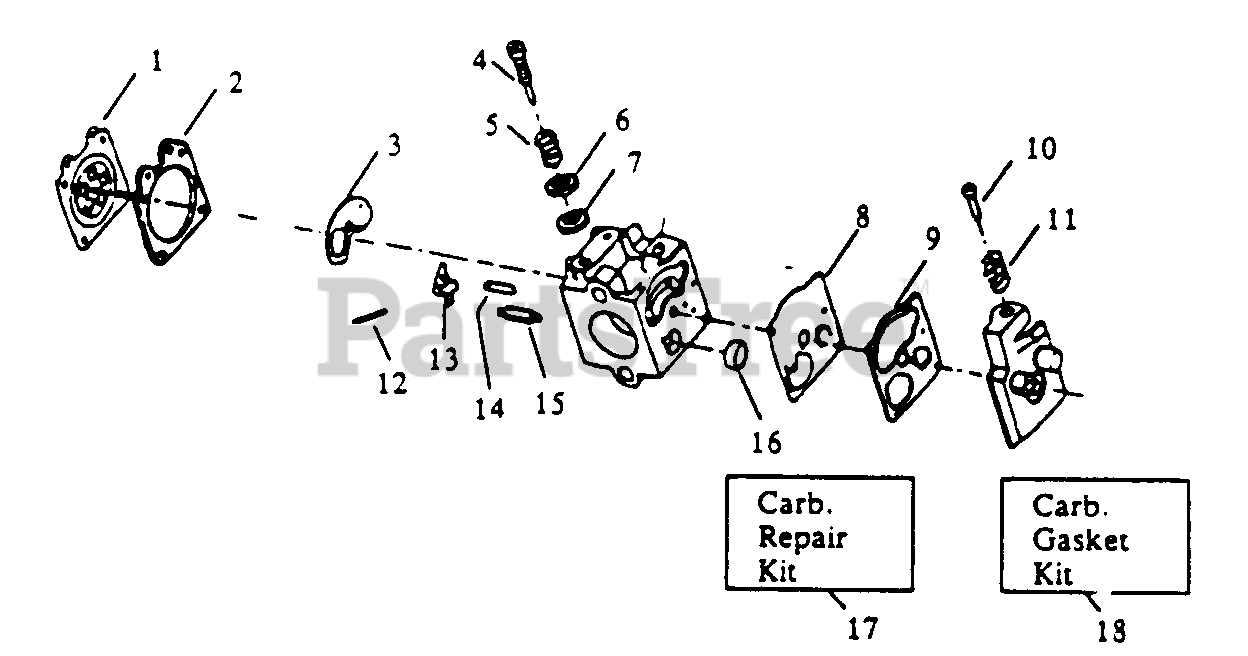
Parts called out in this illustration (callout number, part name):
1	Metering Diaphragm
2	Metering Diaphragm Gasket
3	Circuit Plate Gasket
4	Mixture Needle
5	Mixture Needle Spring
6	Mixture Needle Washer
7	"O" Ring Mixture
8	Fuel Pump Diaphragm
9	Fuel Pump Gasket
10	Idle Speed Screw
11	Idle Speed Spring
12	Metering Lever Pin
13	Metering Lever
14	Metering Lever Spring
15	Inlet Needle Valve
16	Fuel Inlet Screen
17	Carb. Kwik Repair Kit
18	Carb. Gasket/Diaphragm Kit
